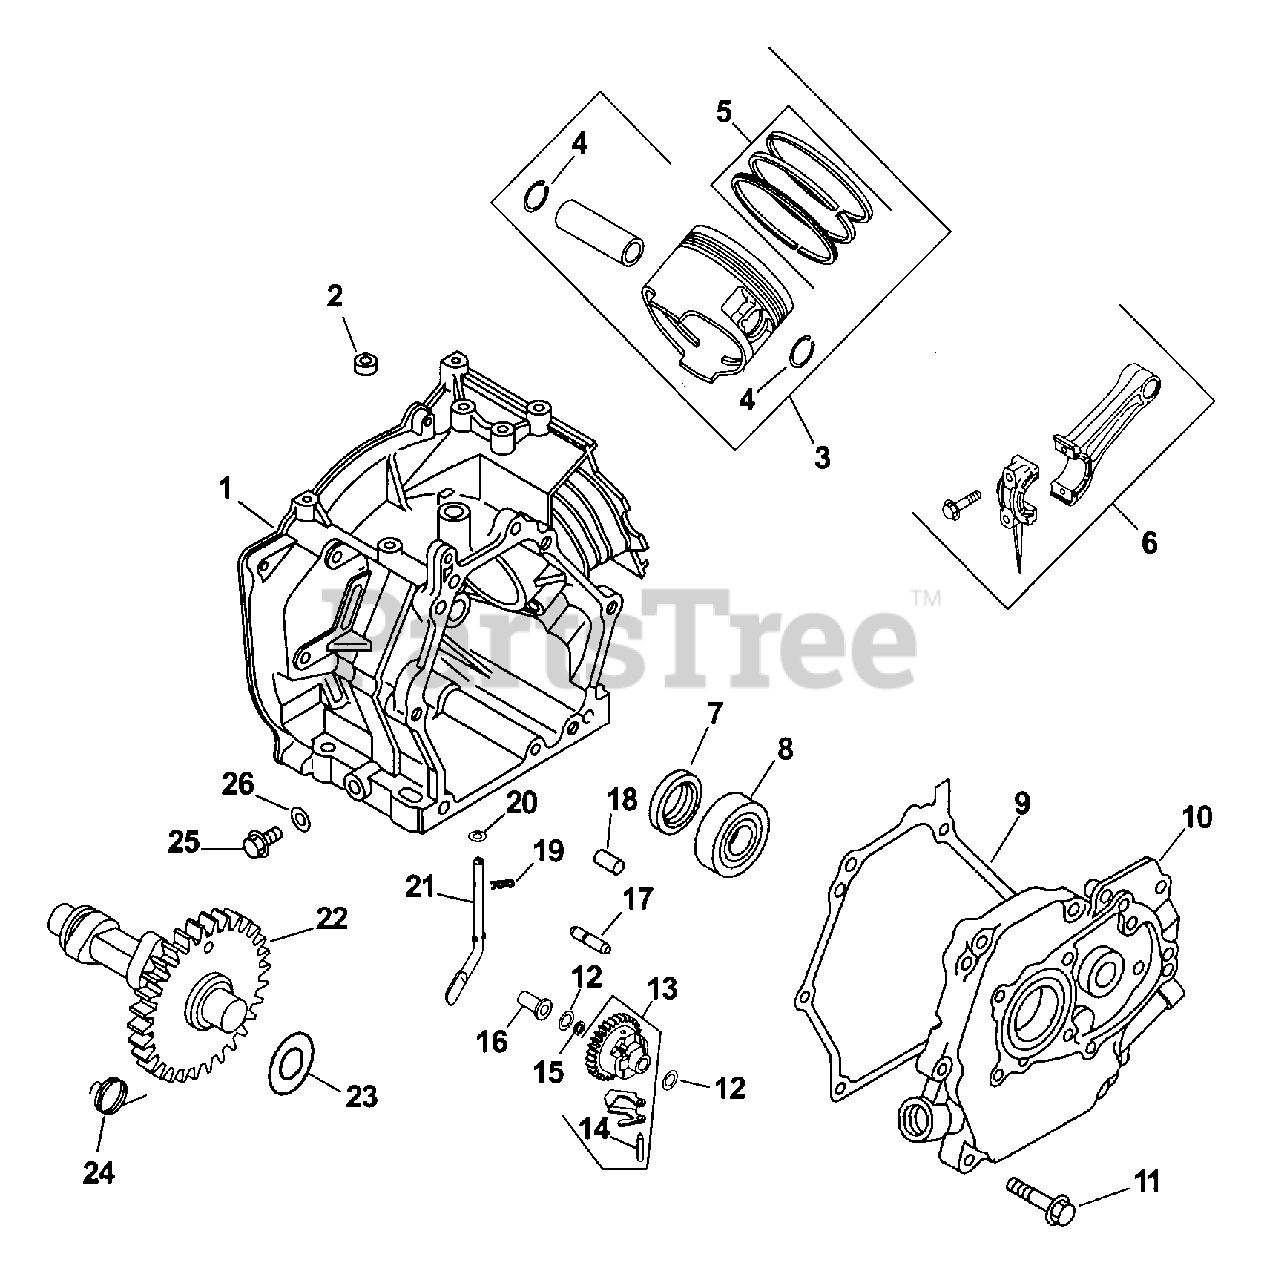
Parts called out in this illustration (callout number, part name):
2	SEAL, GOVERNOR CROSS SHAFT
3	PISTON W/RING SET (STD)
4	RING, RETAINER
5	RING SET, PISTON STD -USE 63 108 16-S
6	CONNECTING ROD
7	SEAL, FRONT OIL
9	GASKET, C.P.
10	CLOSURE PLATE
13	GOVERNOR GEAR ASSEMBLY
14	PIN - USE APPL GOV GEAR ASSY
15	SNAP RING
17	SHAFT, FLYWEIGHT
18	DOWEL PIN
21	SHAFT, GOV CROSS
24	SPRING, ACR
25	PLUG, DRAIN
6310811-S	RING SET, PSTN.25 O/S-USE 63 108 17-S
6310812-S	RING SET, (.50MM) USE 63 108 18-S
6387411-S	PISTON W/RING SET ( .25MM) - DISCONTINUED
6387412-S	PISTON W/RING SET (+.50MM)
